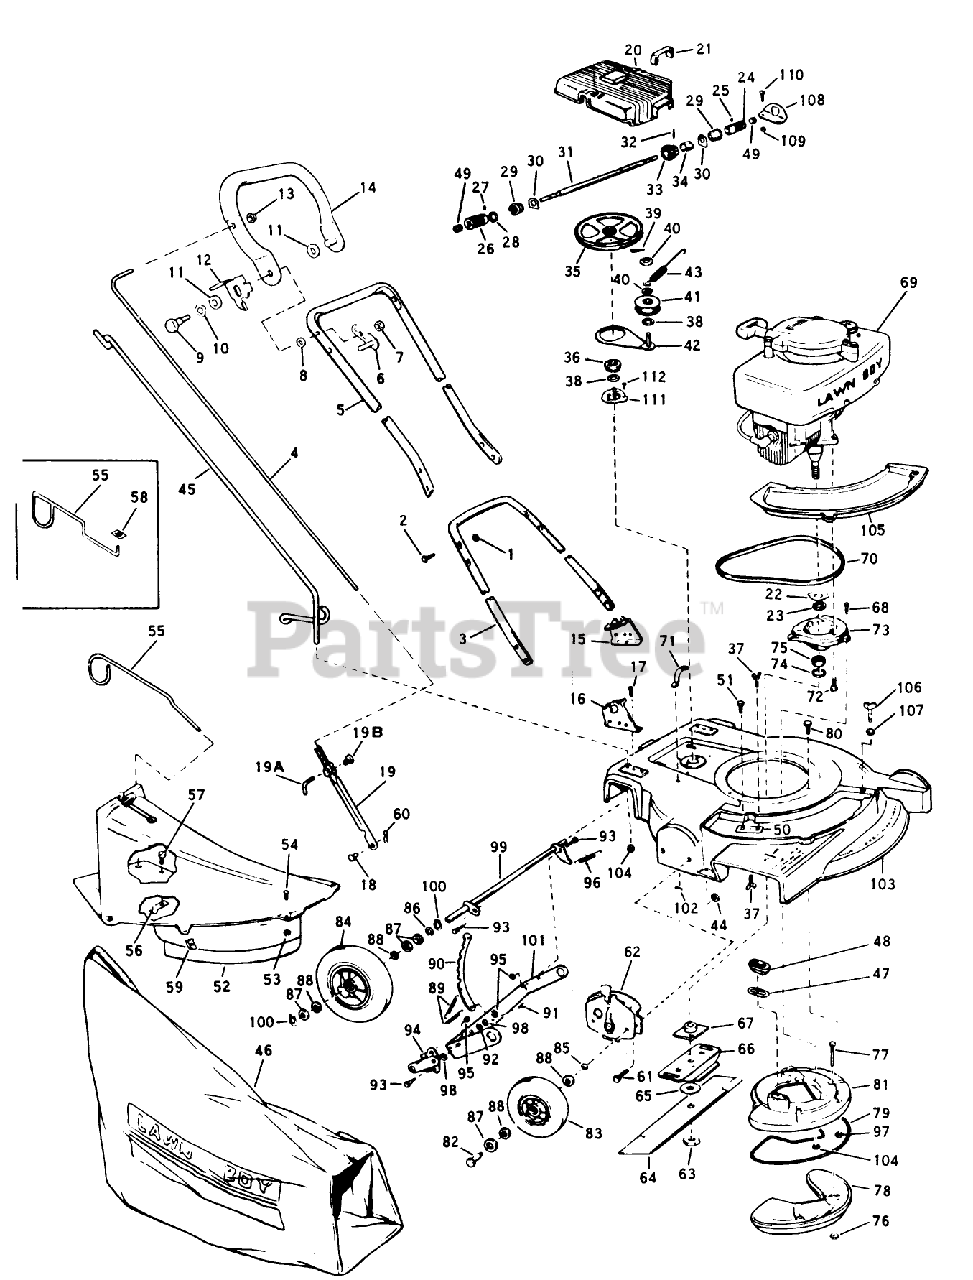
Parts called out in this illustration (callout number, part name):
11	WASHER M
17	SCREW S
35	PULLEY&OILER FELT (13)
46	89802 LB WHOLE GOODS
47	GASKET S
49	GREASE PLUG
52	Chute Skirt Assembly (Includes Hardware)
59	SPEED NUT ARDEN
63	NUT-BLADE
67	PLATE AND COLLAR ASM
76	LOCKNUT E
82	BOLT WHEEL
85	WASHER WROUGHT
93	BOLT RB&W
95	STOP NUT
98	WASHER S
100	RETAINING RING
